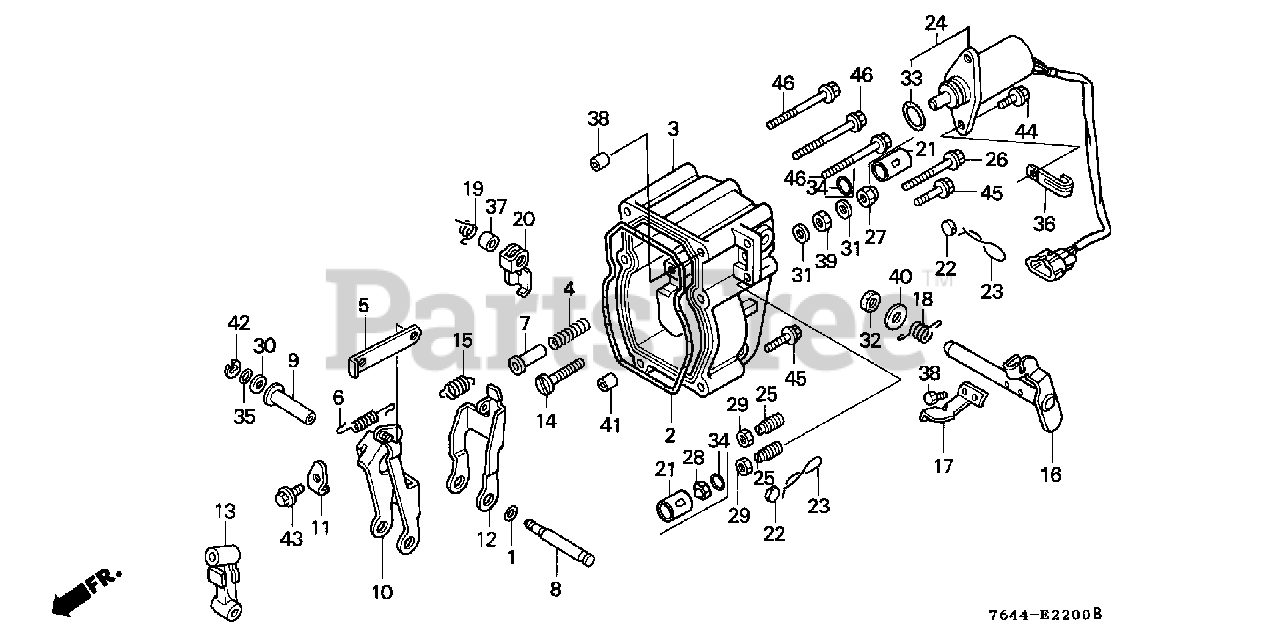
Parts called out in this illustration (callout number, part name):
1	O-RING (4.8X1.9)
2	GASKET, GOVERNOR COVER
3	COVER, GOVERNOR
4	SPRING, START
5	PLATE, CONTROL
6	SPRING, RACK RETURN
7	RETAINER, START SPRING
8	SHAFT, GOVERNOR ARM
9	COLLAR, GOVERNOR ARM SHAFT
10	ARM, RACK CONTROL
11	PLATE, STOPPER
12	ARM, GOVERNOR ADJUSTING
13	ARM, GOVERNOR
14	STOPPER, GOVERNOR ADJUSTING ARM
15	SPRING, GOVERNOR
16	LEVER, CONTROL
17	ARM, CONTROL
18	SPRING, CONTROL LEVER RETURN
19	SPRING, STOPPER ARM RETURN
20	ARM, STOPPER
21	COVER, LOCK
24	SOLENOID ASSY., ENGINE STOP
25	SCREW, ADJUSTING
26	BOLT, FLANGE (6X85)
27	NUT, CAP (6MM)
28	NUT, CAP (6MM)
29	NUT, HEX. (6MM)
30	WASHER, PLAIN (6.5X16X2.6)
31	WASHER (6MM)
32	OIL SEAL (10X16X5)
33	O-RING A (15.5X1.5)
34	O-RING (7.8X1.9) (NOK)
35	O-RING (2.8X1.9) (P3)
36	CLIP, CABLE
37	COLLAR, STOPPER ARM
38	BOLT, HEX. (4X12)
39	NUT, HEX. (6MM)
40	WASHER, PLAIN (10MM)
41	PIN A, DOWEL (8X14)
42	E-RING (4MM)
43	BOLT, FLANGE (6X12)
44	BOLT, FLANGE (6X16)
45	BOLT, FLANGE (6X40)
46	BOLT, FLANGE (6X85)
